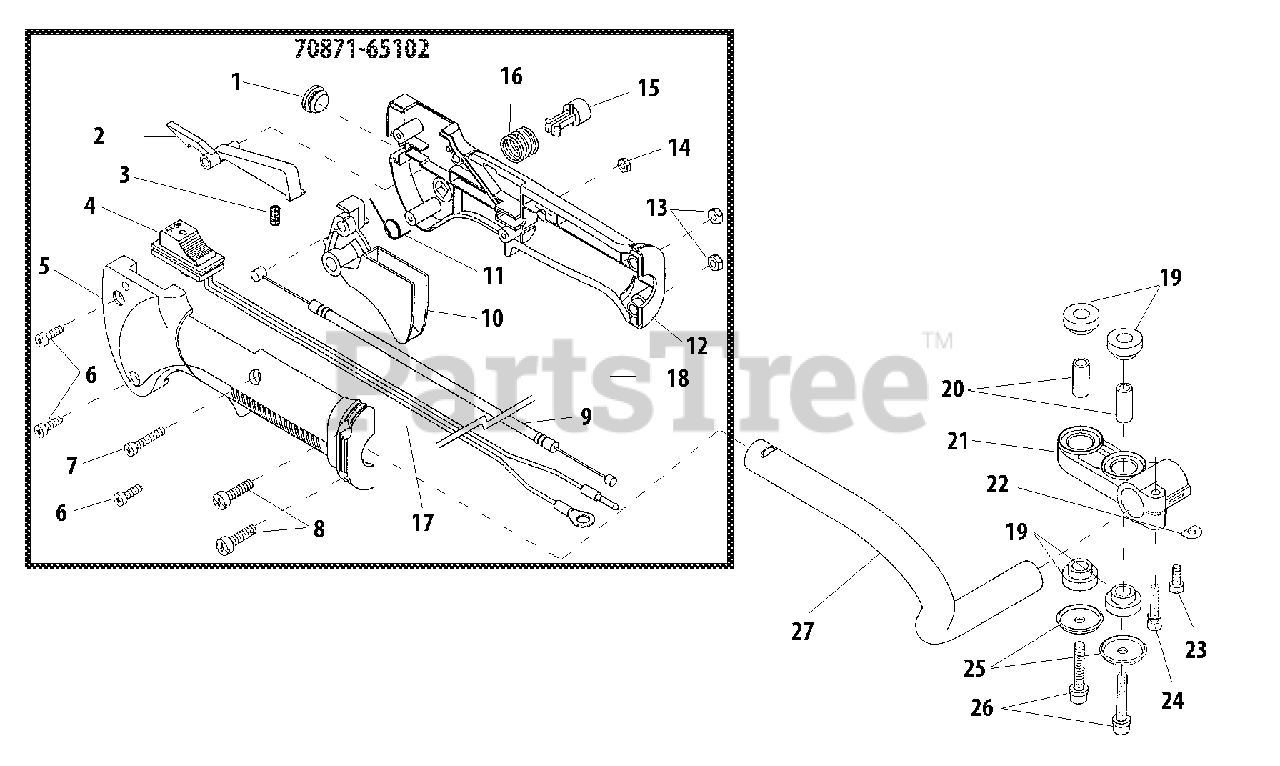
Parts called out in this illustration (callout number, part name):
1	PLUG
2	LEVER, TRIGGER LOCKOUT
3	SPRING
4	IGNITION SWITCH ASSY
5	HANDLE, CONTROL - LEFT
6	SCREW - 4X16 -- TAPPING
7	SCREW - 4X23
8	SCREW - 5X20
9	CABLE, THROTTLE
10	TRIGGER, THROTTLE
11	SPRING
12	HANDLE, CONTROL - RIGHT
13	NUT - 5
14	NUT - 4
15	BUTTON, THROTTLE LOCK
16	SPRING
17	TIE, CABLE
18	TUBE, PROTECTIVE - CORRUGATED
19	CUSHION
20	COLLAR - 6
21	STAY, HANDLE
22	SHIM
23	SCREW - 5X12
24	SCREW - 5X25
25	COVER, CUSHION
26	SCREW - 6X35
27	HANDLE - REAR
70871-65102	THROTTLE LEVER ASSY
